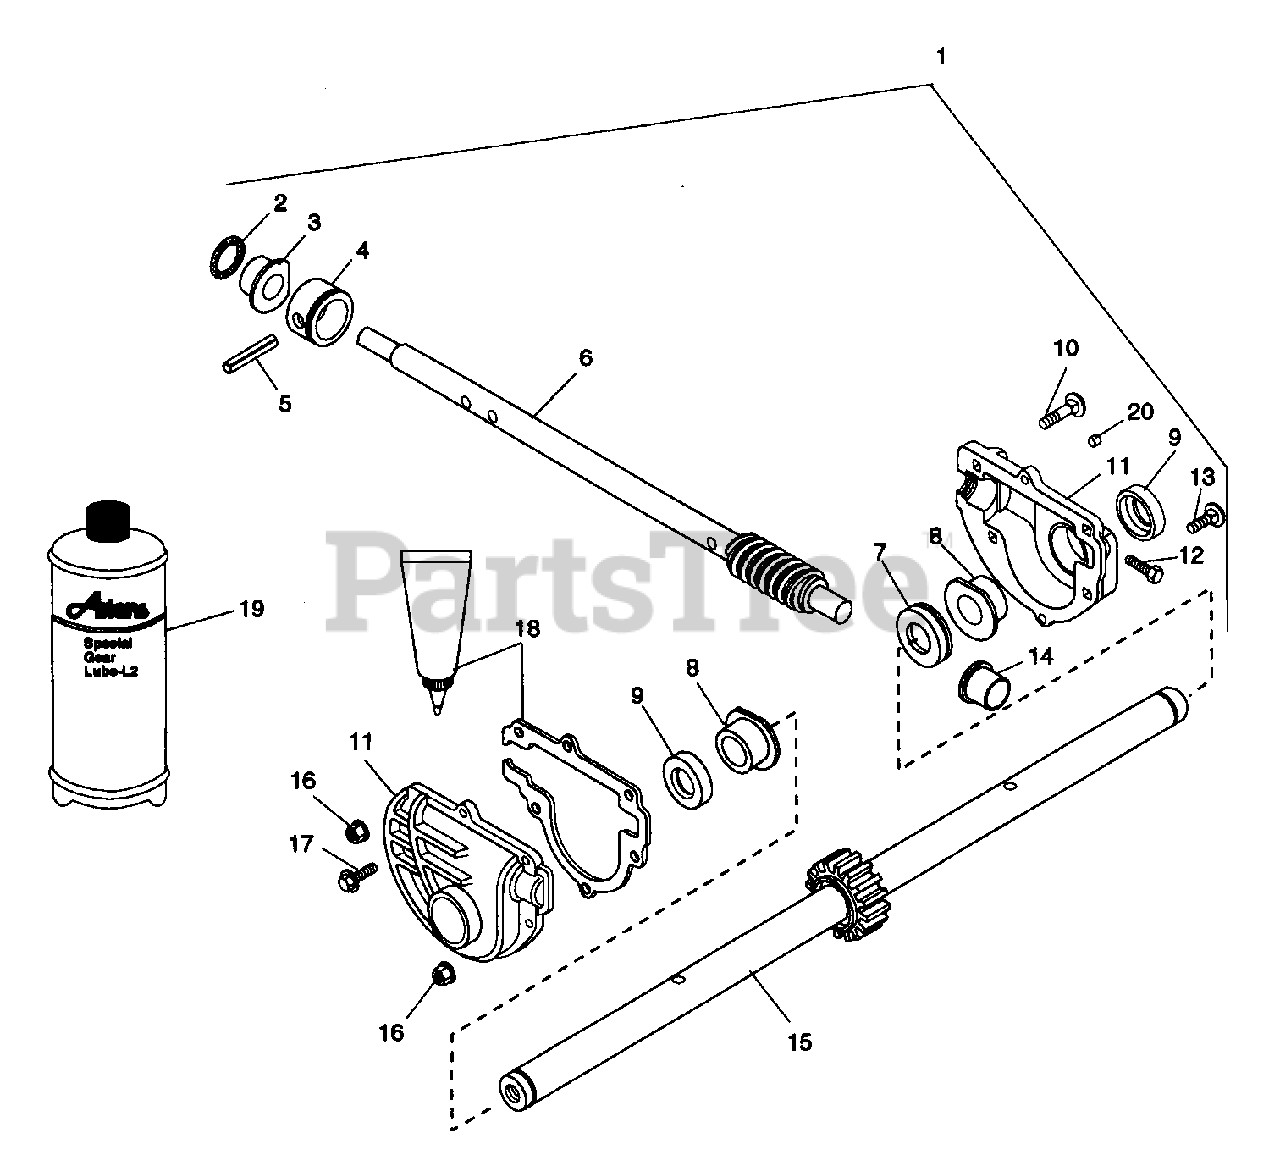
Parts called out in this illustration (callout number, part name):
1	GEAR CASE ASSEMBLY
2	SEAL .750X1.00X.156
2	SEAL .750X1.000X.150
3	BSHG-FLG .750X1.000X.750X1.250
4	THRUST COLLAR
5	PIN-GRV .188X1.25 TP A
6	WORM SHAFT & GEAR ASSY
7	THRUST COLLAR-AUGER SHAFT
8	BSHG-FLG 1.003X1.5X.625
9	SEAL 1.000X1.312X.150
10	BLT-RDHDSQNK .25-20X1.25 GR5PL
11	L. H. GEAR CASE HALF
11	GEAR CASE-LH-LARGE BORE
11	R. H. GEAR CASE HALF
11	GEAR CASE-RH-LARGE BORE
12	SCR-TAP .375-16X .50 HWH PL TR
13	BLT-RDHDSQNK .25-20X1.00 GR5
14	BSHG-FLG .502X1X.750
15	AUGER SHAFT WELD ASSY
16	NUT-LK-FLG .250-20 PL
17	SCR-TAP 10-24X.75 HWH PL TR
18	GASKET
18	LOCTITE 518 GASKET--6ML TUBE
19	BOTTLE ONLY-S.SCREEN.FOR NO.80
20	BREATHER
